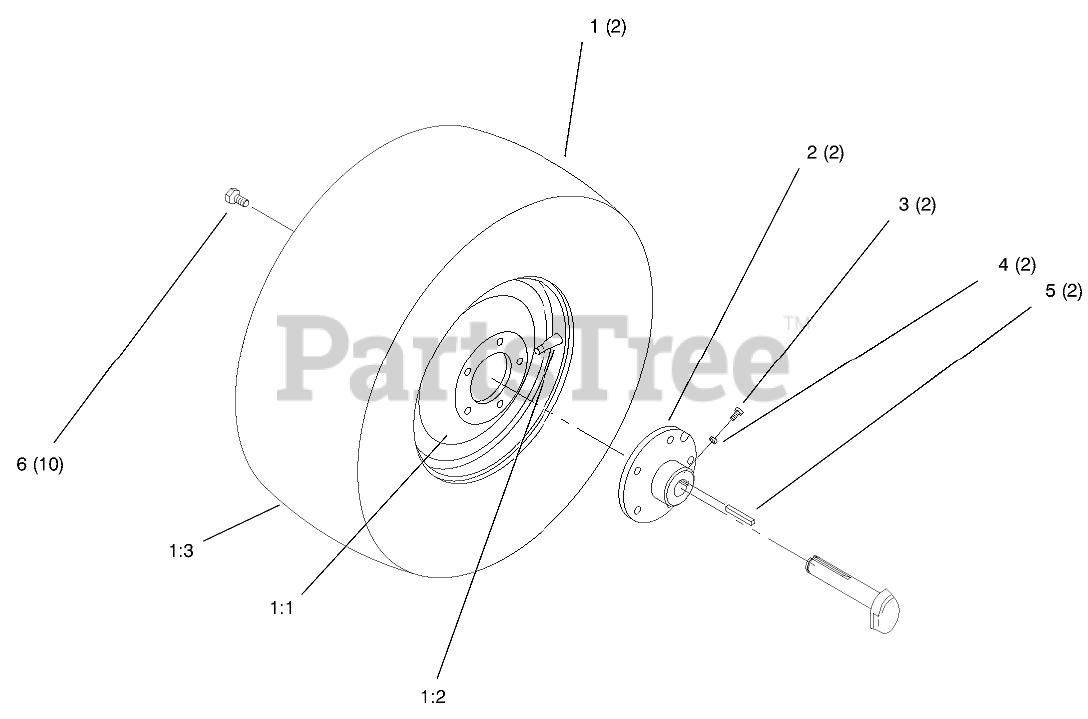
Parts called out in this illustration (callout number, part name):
1	Wheel & Tire ASM Rear
1:1	WHEEL
1:2	VALVE
1:3	TIRE 23 X 10.50-12
2	HUB-WHEEL
3	SCREW-SET, SQH
4	NUT-JAM
5	KEY-SQUARE
6	BOLT-LUG
